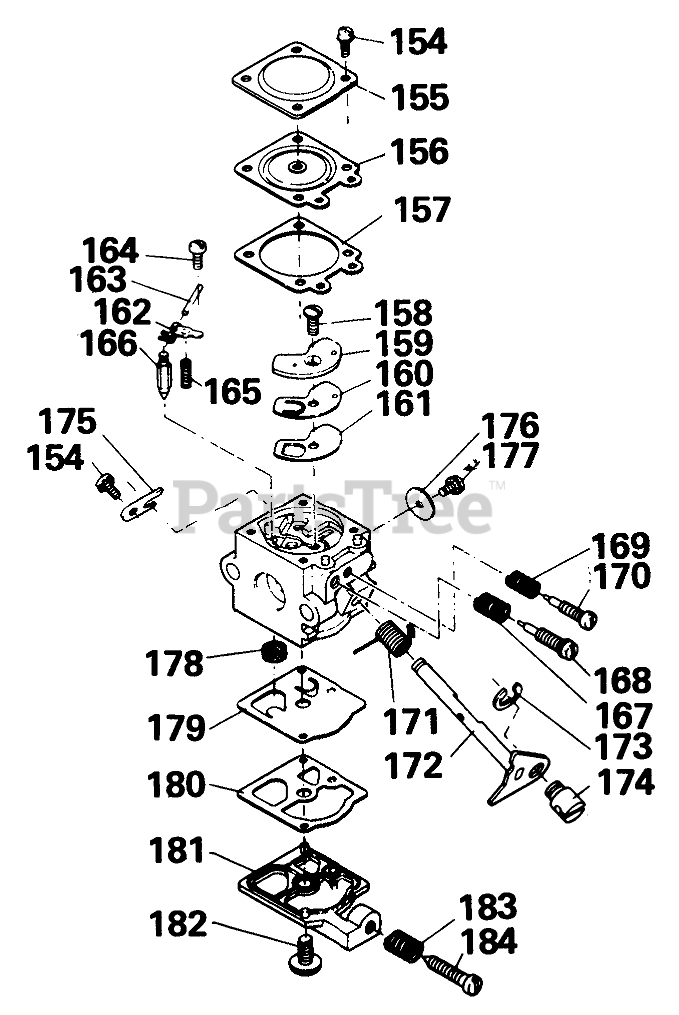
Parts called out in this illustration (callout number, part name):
154	Screw
155	Cover, Diaphragm
156	METERING DIAPHRAGM
157	Gasket, Diaphragm
158	Screw-Circuit Plate
159	Plate, Circuit
160	Diaphragm Circuit Plate
161	Gasket-Circuit Plate
162	Lever Metering
163	Metering Lever Pin
164	Screw-Metering Pin
165	METERING LEVER SPRING
166	INLET NEEDLE VALVE
167	Spring, HS Needle
168	Needle, HS
169	Spring, Needle
170	Needle-Idle
171	Spring-Throttle Lever
172	Shaft Ass-y. Throttle
174	Swivel
175	Clip Throttle Shaft
176	Valve-Throttle
177	Screw
178	Screen Inlet
179	Diaphragm Fuel Pump
180	PUMP GASKET
181	Cover, Fuel Pump
182	Screw
183	Spring, Idle Screw
184	Screw, Idle Adjust
